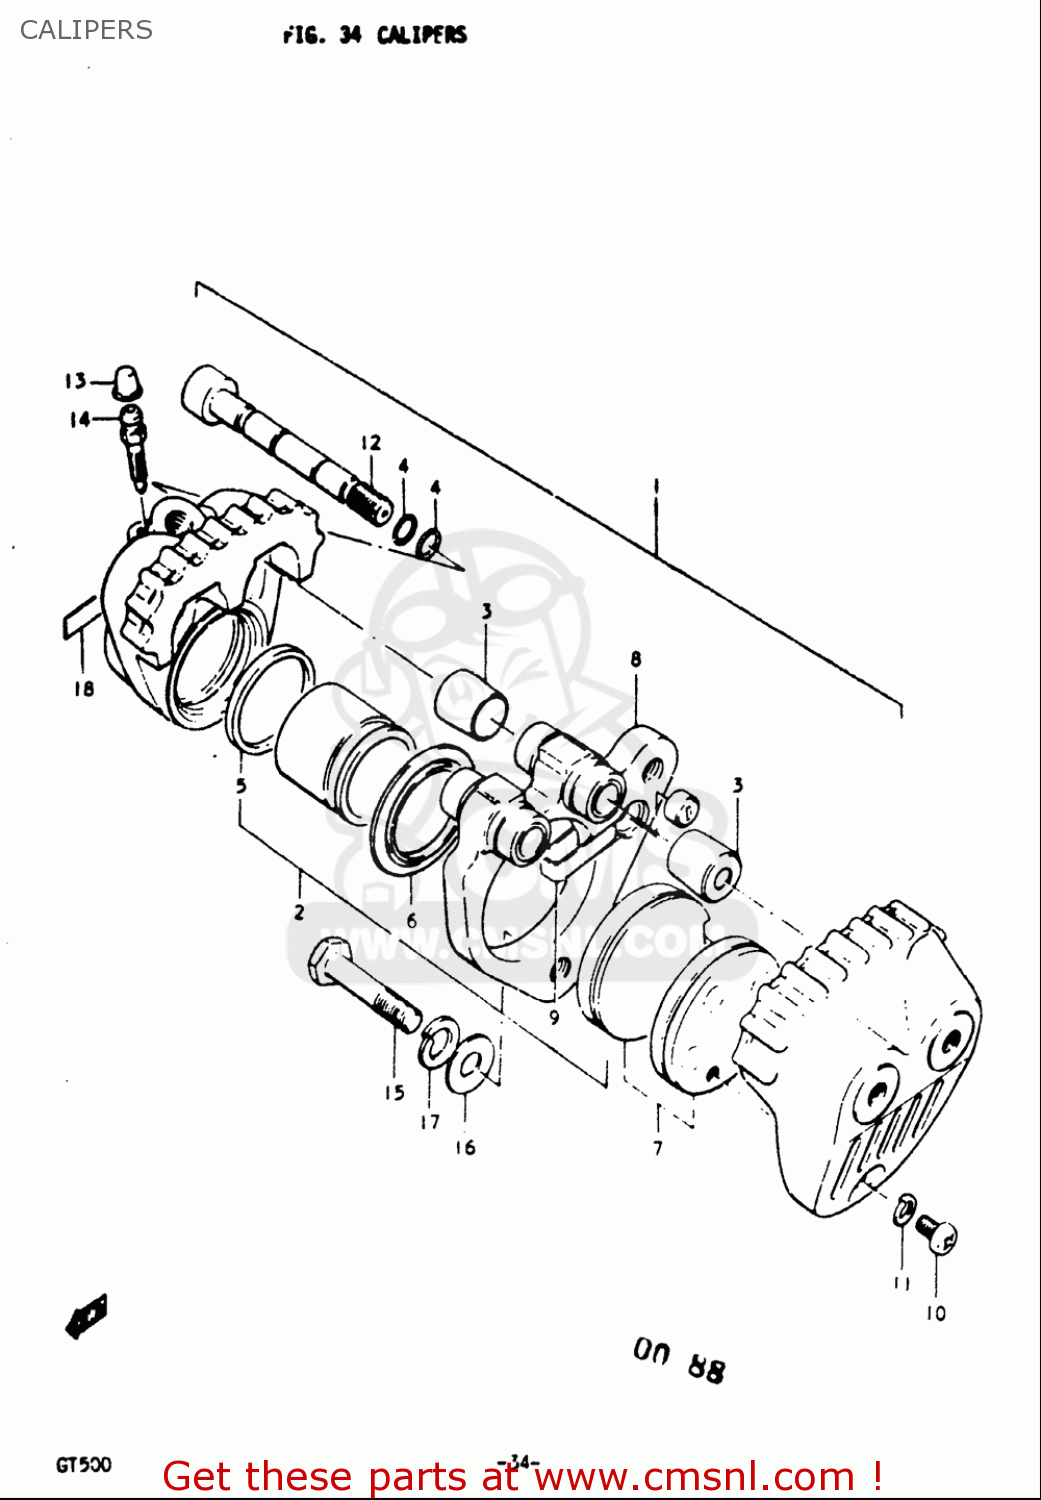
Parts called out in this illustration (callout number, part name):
2	PISTON SET
3	COVER,AXLE DUST
4	O RING,CALIPER AXLE
5	SEAL,PISTON
6	BOOT,PISTON
7	PAD SET (NAS)
10	SCREW
11	WASHER,LOCK
12	AXLE,CALIPER
13	CAP,BLEEDER PLUG
14	BLEEDER
15	BOLT(10X38)
16	WASHER
17	WASHER,LOCK
